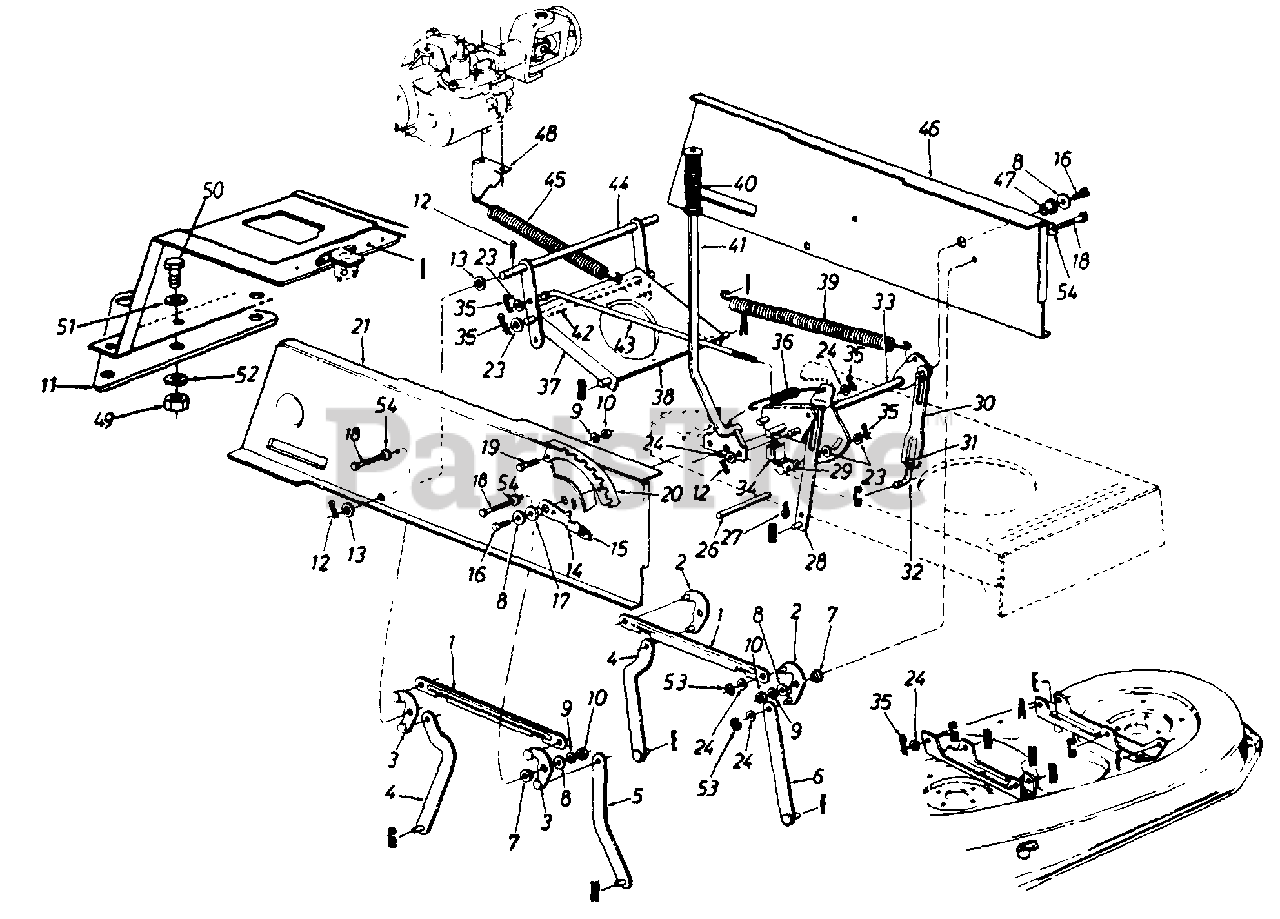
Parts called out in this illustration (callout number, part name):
3	Pivot Link Ass'y.- R.H.
7	Shld. Spacer .318" I.D.
8	Fl-Wash. .344" I.D. x 1.125"
9	L-Wash. 5/16" I.D.
10	Hex Nut 5/16-18 Thd.
11	Hitch Plate Extension
12	Cotter Pin 1/8" Dia.
13	Fl-Wash. .635" I.D. x 1.0" O.D.
14	Height Adj. Stop Lever Ass'y.
15	Knob
16	Hex Wash. TT-Tap Scr. 5/16-18 x .75" Lg.
17	Flange Brg. .63" 1.D.
18	Hex Wash. Hd, Scr. 5/16-18 x .875" Lg.
19	Hex Bolt 5/16-18 x .75" Lg.
20	Index Brkt.
21	Upper Frame - R.H.
23	Fl-Wash. .385" I.D. x .87" O.D.
24	Fl-Wash. .531" I.D. x .93" O.D.
26	Running Board Rod
27	Truss Mach. Scr. #10 x .5" Lg.
31	Hex Nut 1/2-20 Thd. (Gr. 5)
32	Lift Link Adjuster
33	Lift Shaft Ass'y.
34	Safety Switch (Deck)
35	Inter. Cotter Pin 3/8" Dia.
36	Extension Spring
39	Extension Spring
40	Grip (Lift Handle)
41	Deck Lift Handle Ass'y.
42	Shaft 3/8" Dia. x 9.34" Lg.
43	Disengagement Rod
44	Stabilizer Shaft Ass'y.
45	Extension Spring 7.58" Lg.
46	Upper Frame - L.H.
47	Flange Brg. .632" I.D.
49	Hex Nut 7/16-14 Thd. (Gr. 5)
50	Hex Bolt 7/16-14 x 1" Lg.
51	Bell-Wash. .46" I.D.
52	Fl-Wash. .469" I.D. x 1.13" O.D
53	"E"-Ring
54	Bell-Wash. .325" I.D.
